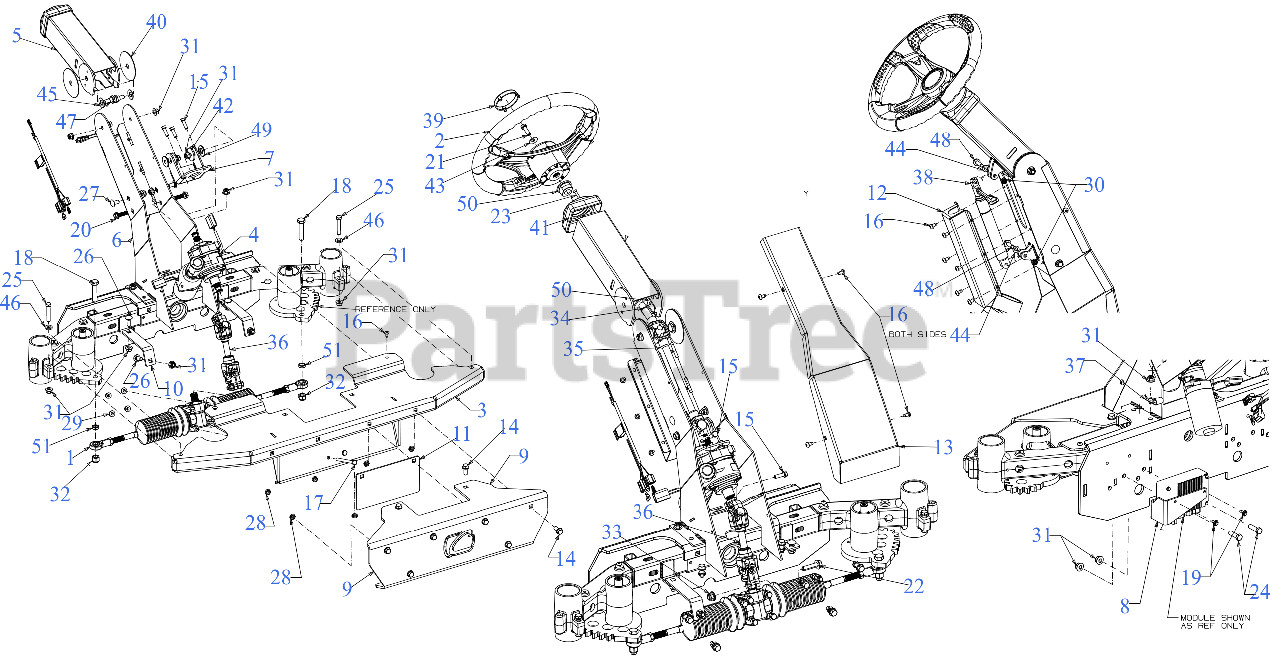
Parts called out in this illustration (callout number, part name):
1	STEERING GEARBOX
2	STEERING WHEEL
4	POWER STEERING CONTROL MODULE
4	POWER STEERING WIRE HARNESS
7	EPS PIVOT BRACKET
8	STEERING MODULE MOUNTING BRACKET
13	COLUMN COVER
14	SCREW 3/8-16 x .875 GR5
15	SCREW M8-1.25 x 25 GR8.8
16	SCREW 1/4-20 x .5
17	SCREW 5/16-18 x 4.00 GR5
18	SCREW 1/2-20 x 2.25
19	SCREW M6-1 x .625
20	SCREW 3/8-16 x 1.25 GR5
21	SCREW 5/16-18 x 1.00 GR5
22	SCREW 3/8-16 x 1.25 GR5
23	SCREW #10-16 x 1.25
24	SCREW 3/8-16 x 1.25 GR5
25	SCREW 3/8-16 x 2.0 GR5
26	CARRIAGE BOLT 3/8-16 x 1.00 GR5
27	CARRIAGE BOLT 3/8-16 x .75
28	JAM LOCK NUT
29	FLANGE LOCK NUT 5/16-18
30	FLANGE LOCK NUT
32	HEX NUT 1/2-20 GR8 NYLON
34	RETAINING RING .570 ID
35	STEERING SHAFT TOP
36	LOWER STEERING SHAFT
37	J TYPE CLIP
38	TILT STEERING DAMPENING CYLINDER
39	STEERING WHEEL CAP
40	COLUMN PLATE
41	STEERING COLUMN COVER
42	FLAT WASHER
43	BELL WASHER .337 X.867 x .057
44	FLAT WASHER .344 x .62
45	TEFLON WASHER .565X1.20
46	FLAT WASHER
47	SHOULDER SCREW .498 DIA x .340
48	SHOULDER SCREW
49	SHOULDER SPACER
50	FLANGE BEARING
